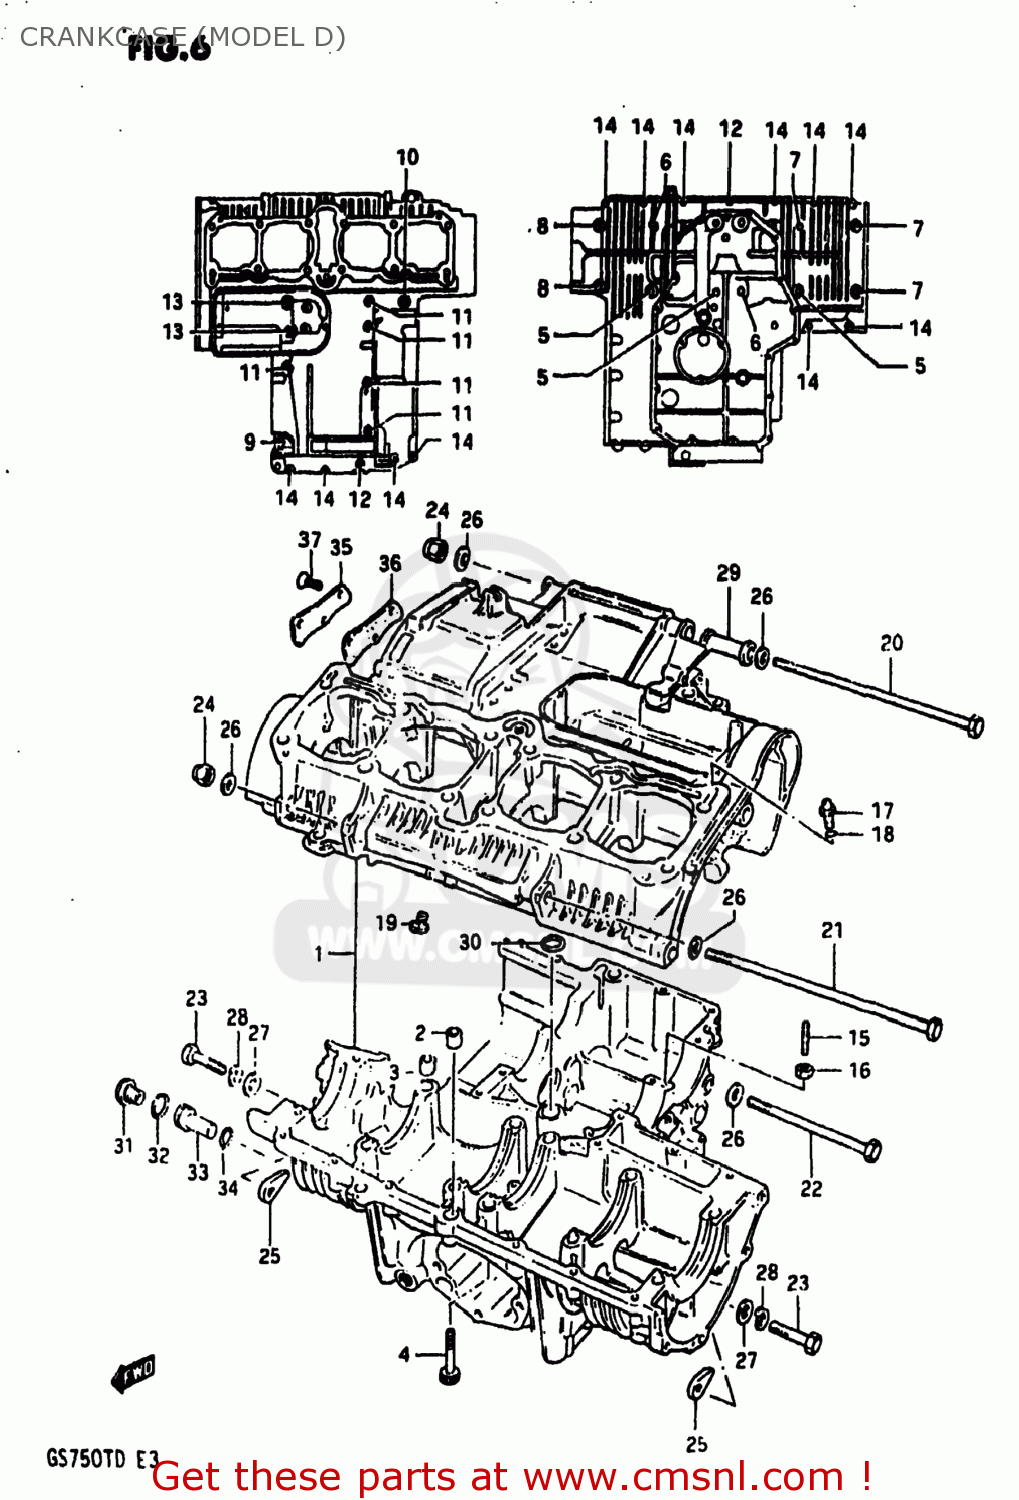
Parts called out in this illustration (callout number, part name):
1	CRANKCASE SET
2	PIN(10.4X13X22)
3	PIN (11X20)(SUS)
4	BOLT
5	BOLT(8X140)
6	BOLT
7	BOLT (8X95)
8	BOLT (8X70)
9	BOLT 8X65
10	BOLT (5X95)
11	BOLT
12	BOLT ,6X60
13	BOLT,UNDER
14	BOLT (6X40)
15	STUD BOLT
16	NUT
17	JET
18	O RING(D:1.05,ID:3.1)
19	JET,AIR
20	BOLT 10X230
21	BOLT 10X250
22	BOLT(10X165)
23	BOLT (10X60)
24	NUT
25	NUT
26	WASHER
27	WASHER (10.5X20X3.2)
28	LOCK WASHER
29	SPACER
30	O RING(D:3.2,ID:12.9)
31	PLUG
32	O RING(D:2.4,ID:17.8)
33	PIN,OIL GALLERY
34	SEAL (D:1.9 ID:9.8)
35	CAP,OIL GALLERY
36	GASKET,OIL GALLERY (MCA)
37	SCREW
